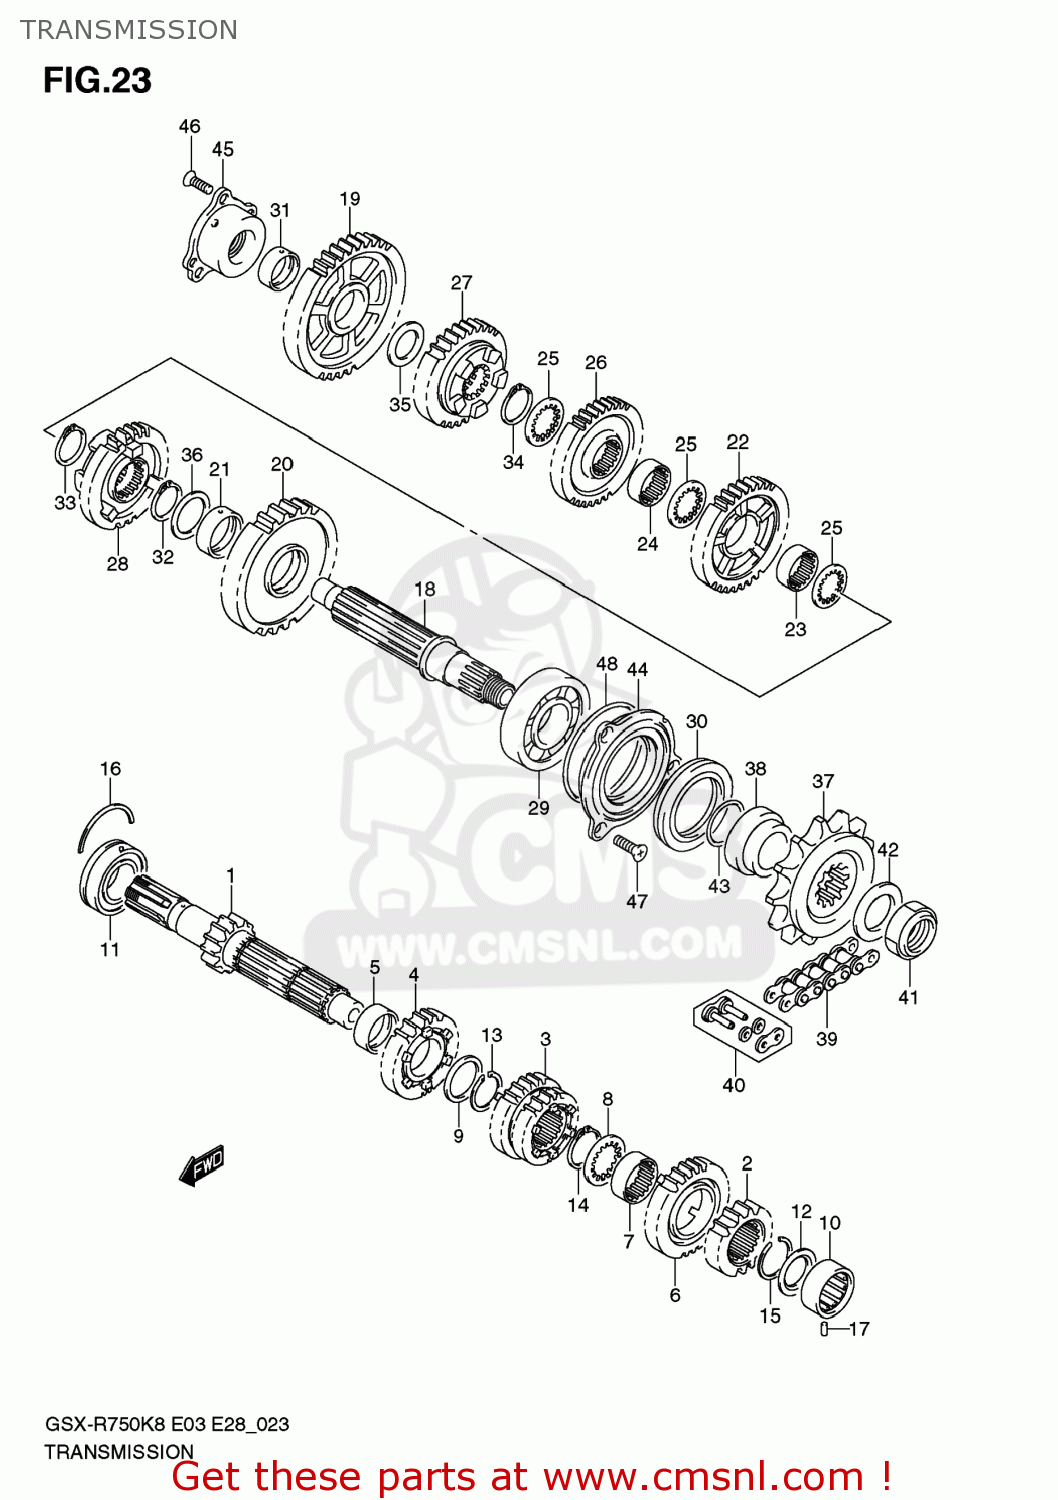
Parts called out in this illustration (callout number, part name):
1	SHAFT,COUNTER
2	GEAR,2ND DRIVE
3	GEAR,3RD & 4TH DRIVE
4	GEAR,5TH DRIVE
5	BUSH,5TH DRIVE GEAR
6	GEAR,6TH DRIVEN(NT:24)
7	BUSH,6TH DRIVE GEAR
8	WASHER,LOCK
9	WASHER(27X36X1)
10	BEARING(20X34X13.5)
11	BEARING(25X62X17)
12	SEAL,OIL(20X31.2X2.7)
13	CIRCLIP
14	CIRCLIP
15	CIRCLIP
16	C RING
17	PIN(6X10)
18	SHAFT,DRIVE
19	GEAR,1ST DRIVEN
20	GEAR,2ND DRIVEN(NT:39)
21	BUSH,2ND DRIVEN GEAR
22	GEAR,3RD DRIVEN
23	BUSH
24	BUSH
25	WASHER,3RD & 4TH DRIVEN
26	GEAR,4TH DRIVEN
27	GEAR,5TH DRIVEN(NT:31)
28	GEAR,6TH DRIVEN
29	BEARING(28X68X18)
30	SEAL,OIL(42X62X7)
31	BUSH(22X26X9)
32	CIRCLIP
33	CIRCLIP
34	CIRCLIP
35	SHIM(22X34X1)
36	WASHER(27X36X1)
37	SPROCKET,ENGINE(17T)
38	SPACER,ENGINE SPROCKET
39	CHAIN,DRIVE
40	JOINT SET,DRIVE CHAIN
41	NUT
42	WASHER(25X41X3)
43	O RING(D:2.4,ID:23.7)
44	RETAINER,DRIVE SHAFT BEARING,L
45	HOUSING,DRIVE SHAFT SET
46	SCREW(6X20)
47	SCREW(6X20)
48	O RING(D:1.9,ID:67.5)
